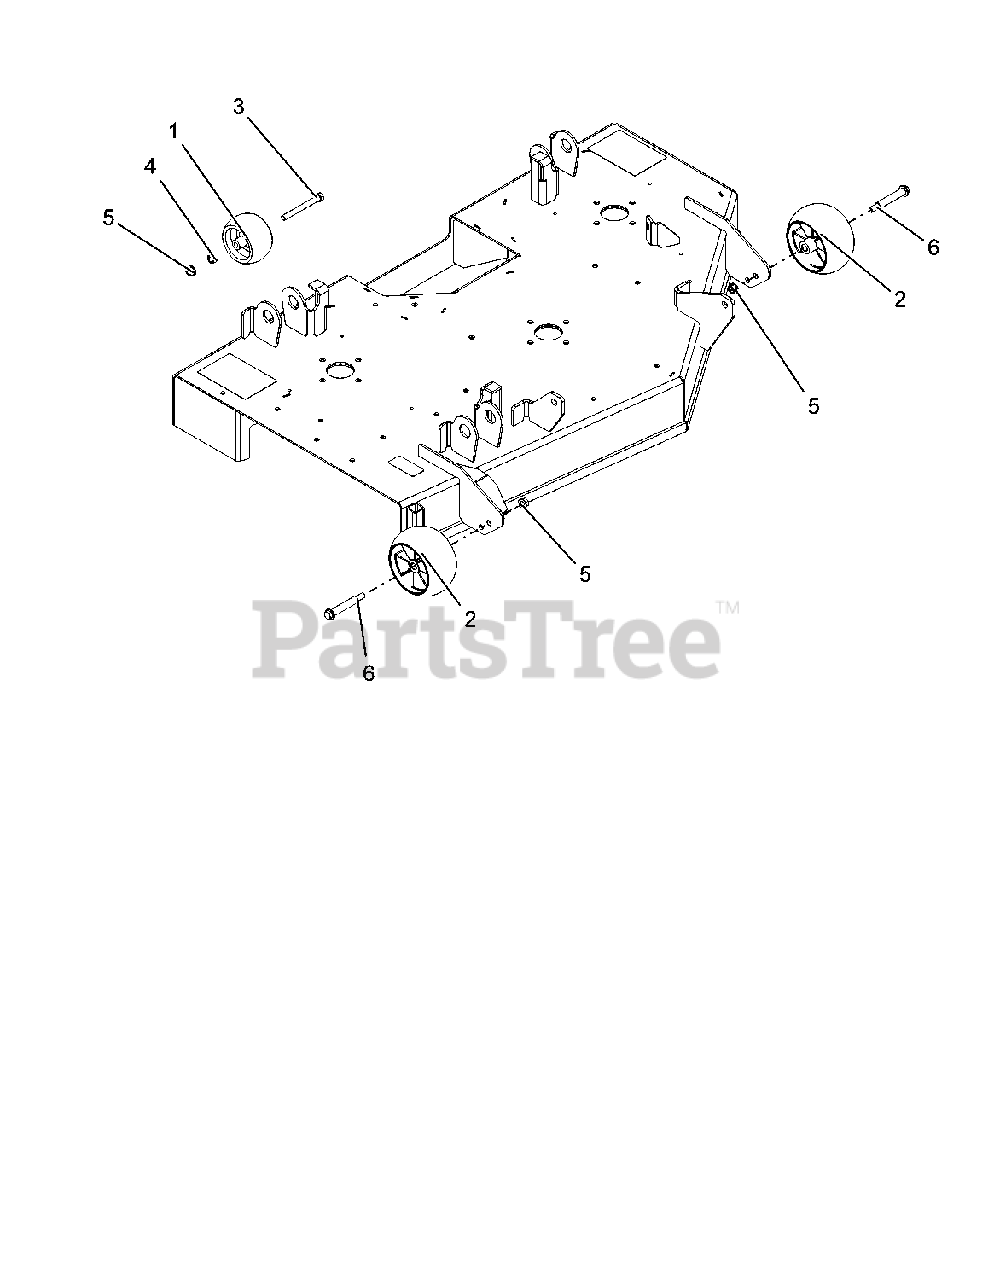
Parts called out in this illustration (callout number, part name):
2	ANTI-SCALP WHEEL - 5XOS
3	BLT-HEX .38-16X3.50 GR5 YWZC
4	NUT-HEX .38-16 YWZC
5	NUT, LK-TOP-FLG .38-16 YWZC
6	BLT-SHLDR .38-16X2.50 HWH G5YZ
